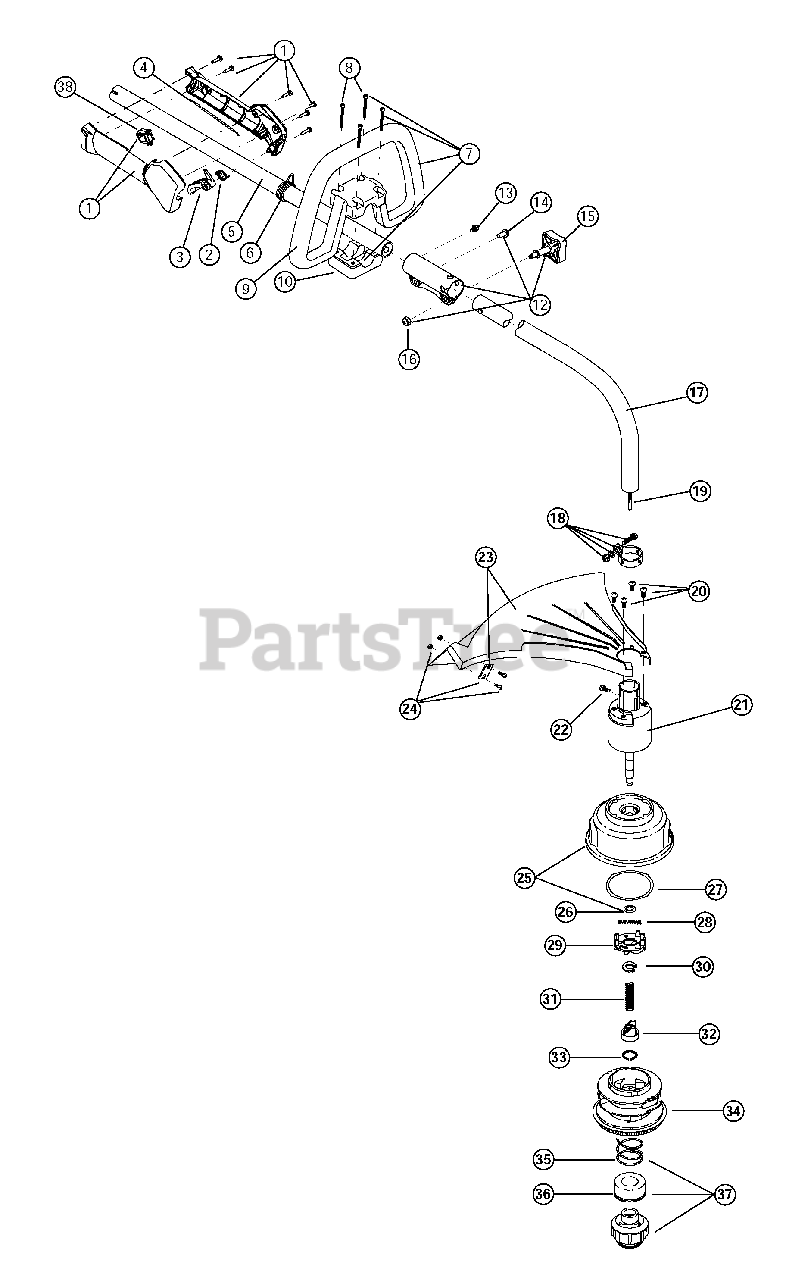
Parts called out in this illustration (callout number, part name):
1	Throttle Housing and Trigger Assembly
2	Throttle Trigger Spring
3	Throttle Trigger
4	Throttle Cable Assembly
5	Upper Drive Shaft Housing Assembly
6	Harness Clip
7	Deluxe D-Handle Assembly
9	Deluxe D-Handle
10	Bottom Clamp
11	EZ-Link Coupler
14	Adjustment Knob
15	Knob Retaining Nut
16	Lower Drive Shaft Housing Assembly
17	Lower Clamp Assembly
18	Lower Flexible Drive Shaft
19	Shield Mounting Screw
20	Bushing Housing Assembly
21	Anti-Rotation Screw
22	Shield and Blade Assembly
23	Blade Assembly
24	Outer Spool and Eyelet Assembly w/Retainer
25	Retainer
26	Thrust Washer
27	Small Spring
28	Slider
31	Plunger
33	Inner Reel
34	Large Spring
35	Foam Seal
36	Bump Head Knob Assembly
37	Switch Assembly
